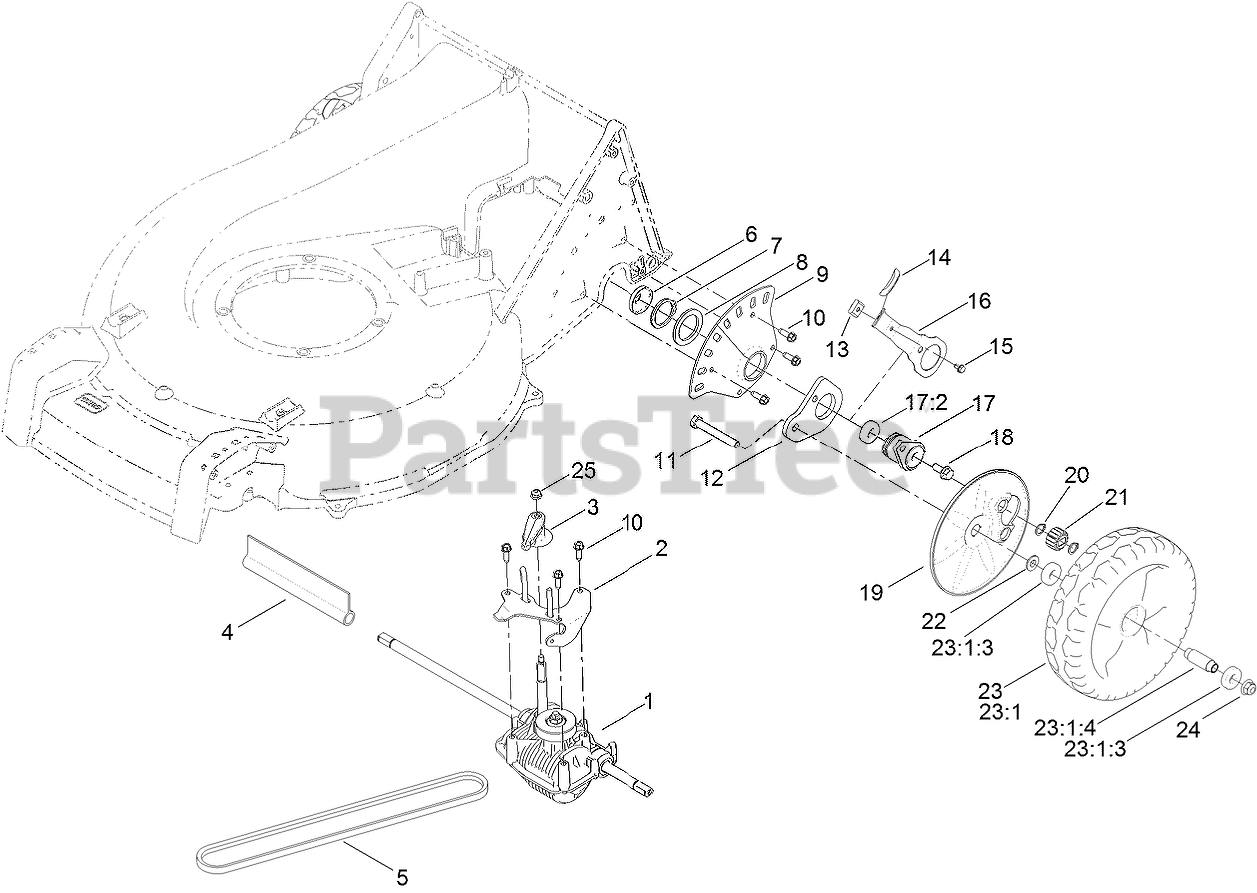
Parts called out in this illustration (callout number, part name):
1	TRANSMISSION-HD
2	GUIDE-BELT
3	LEVER-SHIFT
4	COVER-SHAFT, TRANSMISSION
5	BELT-V
6	COVER-BEARING
7	RING-RETAINING
8	Washer-Thrust
9	PLATE-HOC, REAR
10	SCREW-HWHTF
11	SCREW-HH
12	ARM-PIVOT, REAR
13	KEY-ARM, SPRING
14	KNOB-LEVER, HOC
15	SCREW-HWH
16	ARM-SPRING, REAR
17	RETAINER ASM
17:2	BEARING-WHEEL
18	SCREW-HWH
19	COVER-WHEEL
20	RING-RETAINING
21	GEAR-PINION, 15T
22	SPACER-COVER, WHEEL
23	WHEEL ASM
23:1	WHEEL
23:1:3	BEARING-WHEEL
23:1:4	SPACER
24	NUT-HF, NI
25	NUT-HF
